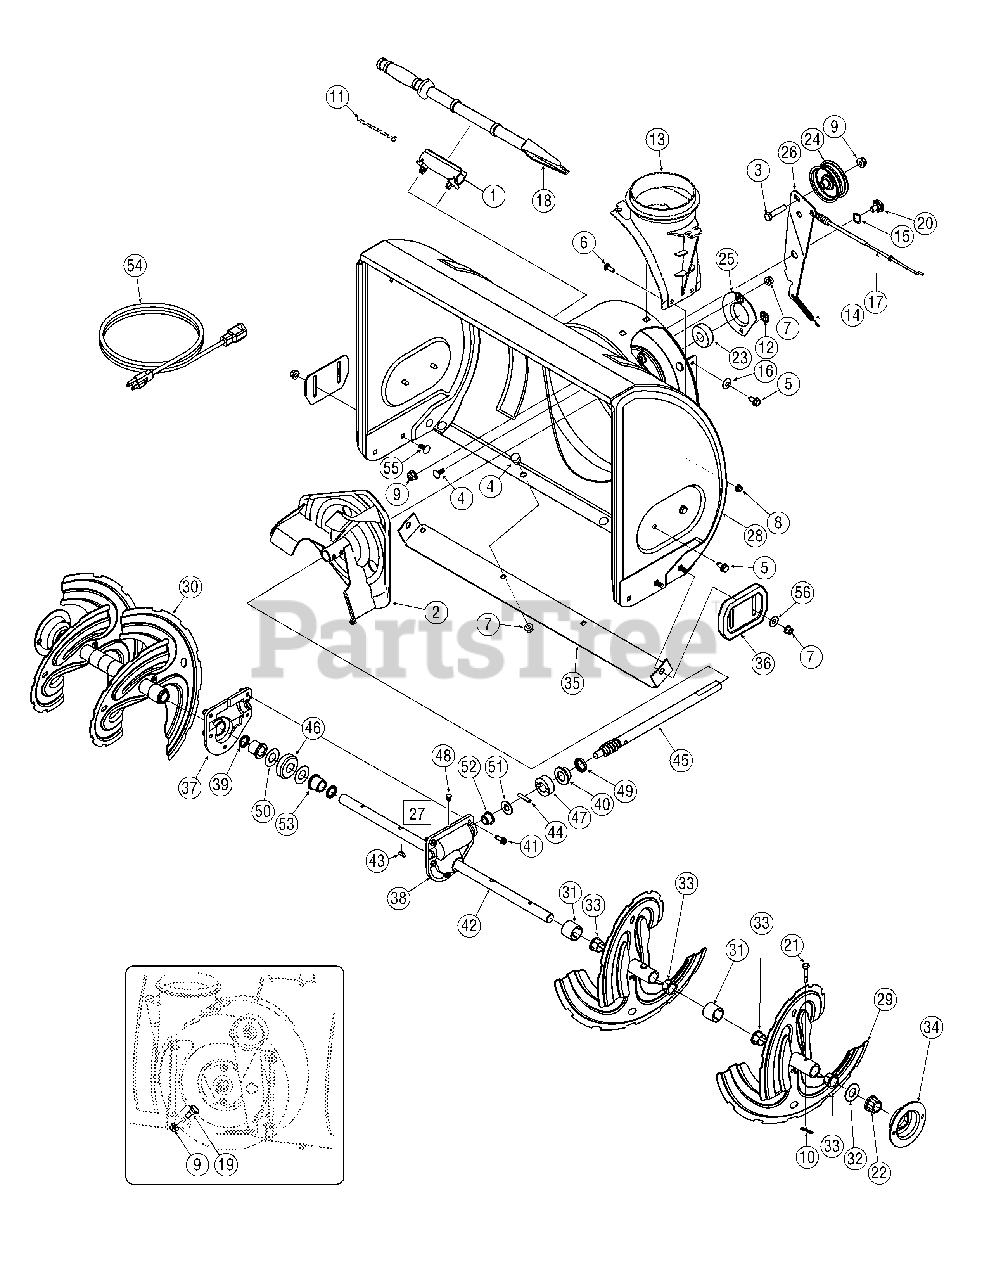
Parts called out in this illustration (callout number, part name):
1	Snow Removal Tool Mount
2	Impeller Assembly, 12" Dia.
3	Hex Screw, 3/8-16, 1.75, Gr5
4	Bolt, Carriage, 5/16-18, .750 Gr1
5	Screw, 5/16-18, 0.750
6	Screw, Carriage, 1/4-20, .750, Gr5
7	Nut, Flange Lock, 5/16-18, Nylon
8	Nut, Flange Lock, 1/4-20, Nylon
9	Nut, Flange Lock, 3/8-16, Nylon
10	Cotter Pin, Bow-tie
11	Cable, Tie, 3/16 x .05 x 7.4
12	Nut, Push-on, .25 Dia
13	Chute, Adapter 5" Dia
14	Spring, Extension, .38 OD x 4.59
15	Washer, Wave, .625 x .885 x .015
16	Washer, Bell, .340 x .872 x .060
17	Clutch Cable, Auger, 47.23"
18	Snow Removal Tool
19	Screw, Shoulder, .498 x .34, 3/8-16
20	Screw, Shoulder, .625 x .17, 3/8-16
21	Shear Pin, .25 x 1.50
22	Bearing, Hex Flange x .75 ID
23	Bearing, Ball, .75 ID x 1.85 OD
24	Flat Pulley, Idler, 2.75 OD
25	Housing, Bearing, 1.85 ID
26	Bracket, Auger Idler w/ Brake
27	Gearbox Assembly, Auger, 24"
28	Housing Assembly, Auger 24"
29	Spiral Assembly, LH
30	Spiral Assembly, RH
31	Spacer, 1.25 OD x .75 ID x 1.00
32	Washer, Flat, .76 x 1.49 x .06
33	Bushing, Flange, .80 ID x .91 OD
34	Housing, 1" Hex Bearing
35	Shave Plate, 2.25 x 23.66
36	Slide Shoe, Polymer
36	Standard Polymer Reversible Shoe Kit
37	Housing, Auger, RH
38	Housing, Auger, LH
39	Seal, Oil, .750 x 1.00 x .125
40	Bearing, Flange, .75 x 1.0 x .59
41	Screw, Self-tapping, 1/4-20, 0.750
42	Axle, Auger, 24"
43	Key, Hi-pro 3/16 x 5/8
44	Pin, Dowel, .25 OD x 1.2
45	Shaft, Worm .75 OD
46	Gear, Worm 20T
47	Collar, Thrust
48	Plug, 1/4 x .437
49	Seal, Oil, .75 x 1 x .131
50	Washer, Flat, .760 ID x 1.5 OD
51	Washer, Flat, .51 x 1.12
52	Bearing, Flange, .75 x 1.0 x .925
53	Bearing, Flange, .75 x 1.00 x .975
54	Extension Cord, 110V
55	Screw, Carriage, 5/16-18 x 1.00
56	Washer, Flat, .349 x .879 x .063
